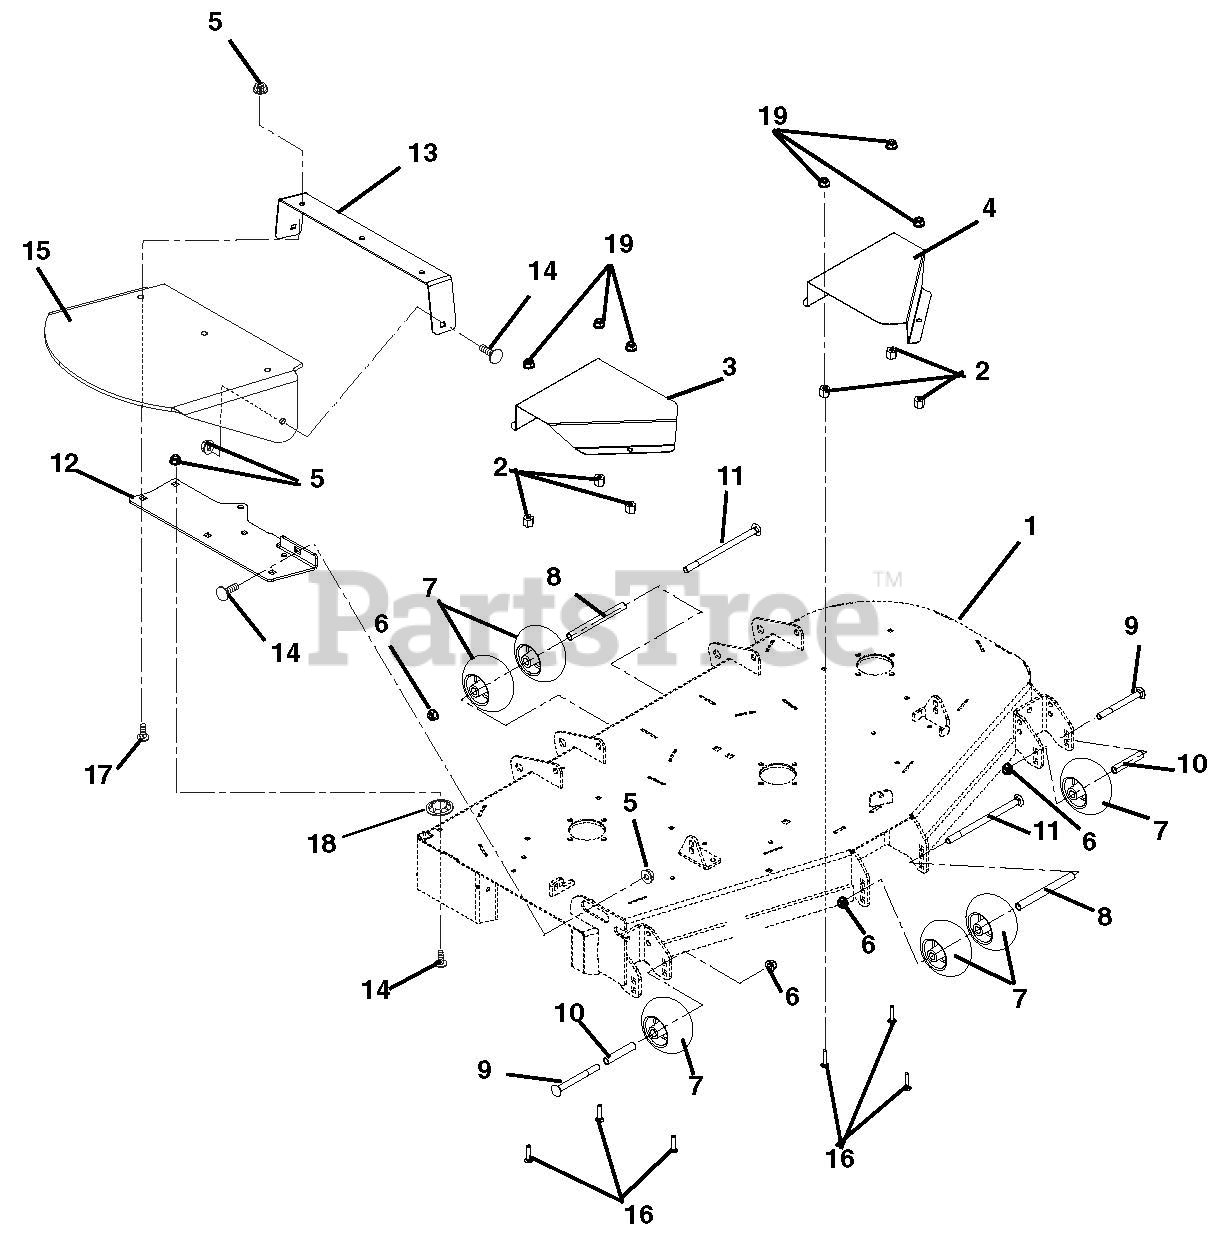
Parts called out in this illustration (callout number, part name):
1	Weldment, 60" Side Discharge Deck
1	Weldment, 52" Side Discharge Deck
1	44" Side Discharge Deck Weldment
1	48" Side Discharge Deck Weldment
2	Nut, Heavy Hex .38-16
3	Guard, 60" Right Hand Spindle Sheave
3	Guard, 48"-52" Right Hand Spindle Sheave Guard
4	Guard, 60" Left Hand Spindle Sheave
4	Guard, 44"-52" Left Hand Spindle Sheave
5	Nut, .38-16 Nyloc Flange
6	Nut .50-13 Nyloc Flange
7	Anti-Scalp Wheel
9	Bolt, Round Head Square Neck .50-13 x 5.00
10	Spacer, .510 x .625 x 3.35
11	Bolt, Round Head Square Neck .50-13 x 8.50
12	Plate, Discharge Chute Support
13	Rubber Discharge Chute Support
14	Bolt, Round Head Square Neck .38-16 x 1.00 Grade 5
15	Chute, Rubber Discharge
16	Bolt, Hex .38-16 x 1.25 Grade 5
17	Bolt, Round Head Square Neck .38-16 x 1.25 Grade 5
18	Retainer, .38 Push-On
19	Nut, Flange .375-16
